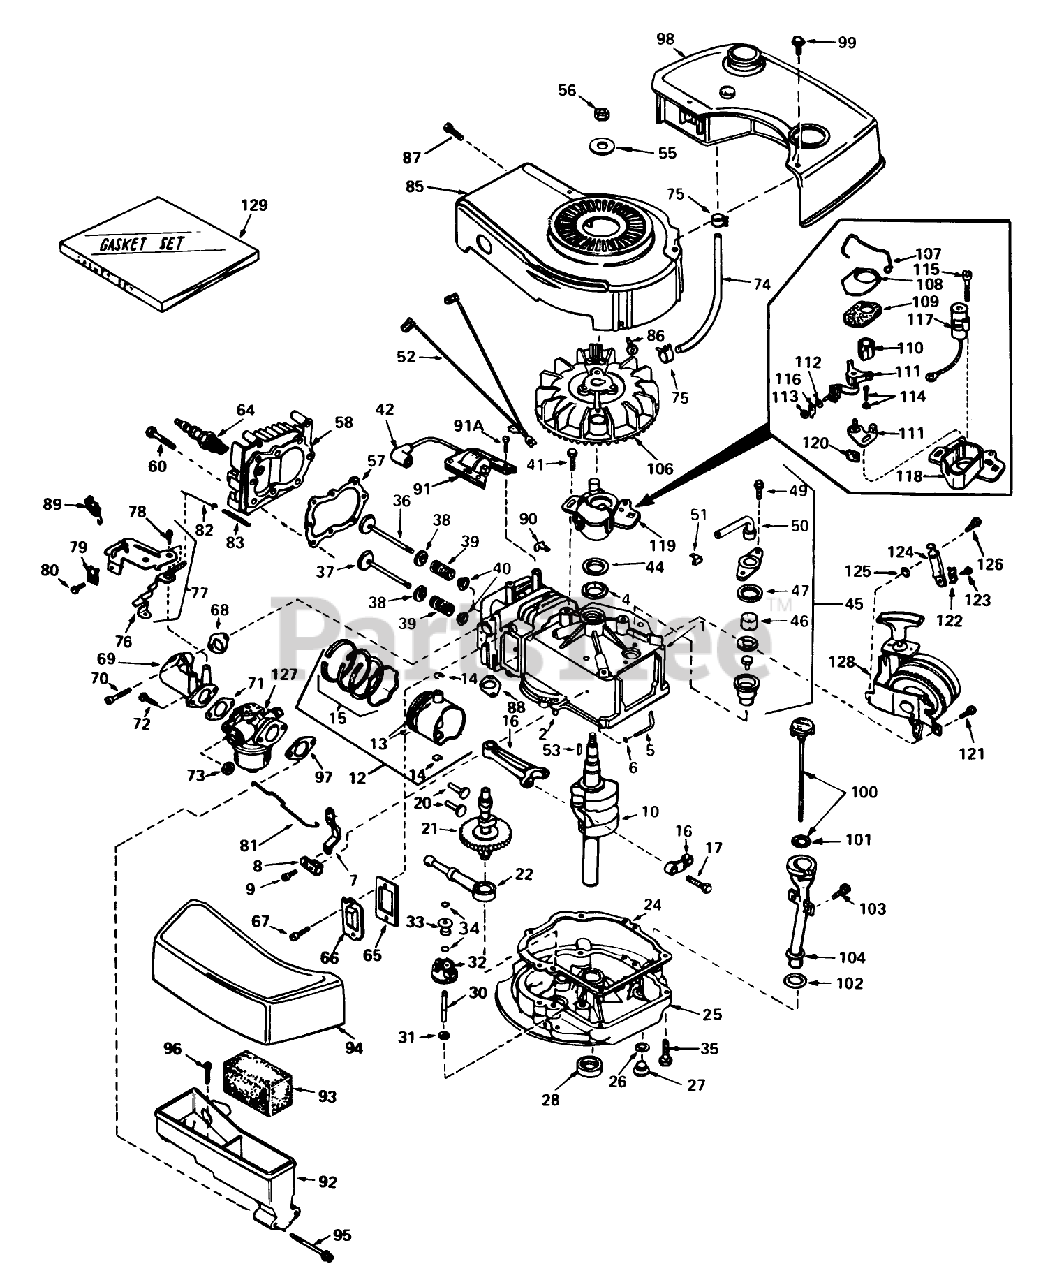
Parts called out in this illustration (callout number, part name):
1	Cyiinder Assy. (Incl. Ref. #2, 4 105)
2	Pin-Dowel
4	Seal-Oil
5	Rod, Governor (Incl. No. 36)
6	Washer-Flat
7	Governor Lever
8	Clamp-Lever, Governor
9	Screw
10	Crankshaft
12	Piston, Pin Ring Assy. (Std.)(Incl. Ref. #13A, 14 15)
12	Piston,Pin Ring Assy. (.010 over-size)(Incl. Ref. #13A, 14 15)
12	Piston, Pin Ring Assy. (Incl. Nos. 13A, 14 15)(.020 oversize)
13	Piston Pin Assy. (Incl . Ref. . #14) (Std.)
13	Piston Pin Assy. (Incl. Ref. #14) (.010 Oversize)
13	Piston Pin Assy. (.020 oversize) (Incl. Ref. #14)
14	Ring-Retaining, Piston Pin
15	Ring Set Piston (Std.)
15	Ring Set Piston (.010 Oversize)
15	Ring Set Piston (.020 Oversize)
16	Rod Assy., Connecting (Incl. Ref. #17)
17	Bolt-Rod, Connecting
20	Lifter-Valve
21	Camshaft(Mech.Comp. Release)
22	Oil Pump ASM
24	Gasket, Mounting
25	Flange Assy., Mounting (Incl. Ref. #26thru 30)
26	Gasket-Oil Drain
27	Plug Oil Drain
28	Seal Oil
30	Shaft-Governor
31	Washer-Flat
32	Governor Gear ASM
33	Spool-Governor
34	Ring-Retaining
35	Screw (1/4-20 x 1-1/4)
36	Valve, Intake (Incl. Ref. #38, 39 40) (Std.)
36	Valve, Exhaust (1/32" Oversize) (Incl. Nos. 8, 9 10)
37	Valve, Exhaust (Standard) (Incl. Nos. 8, 9 10)
37	Valve, Exhaust (1/32" Oversize) (Incl. Nos. 8, 9 10)
38	Cap-Upper Valve Spring
39	Spring-Valve
40	Cap-Valve, Spring
41	Screw
42	Cover-Spark Plug
44	Gasket Stator
45	Breather Assy. (Incl. Ref. #46, 47, 49, 50 51 )
46	Element-Breather
47	Gasket-Breather
49	Screw (10-24 x 9/16)
50	Tube, Breaker
51	Clip, Breather
52	Wire Ground
53	682488 LB GRASS HI-
55	Washer-Belleville
56	Nut-Flywheel
57	63573 GIL 42 SNWTHW
58	Dipper-Oil
60	Screw
64	Plug, Spark (J17LM or equiv.)
64	Plug, Spark (Champion RCJ-8)
65	Gasket-Breather
66	Cover-Valve
67	Screw
68	Gasket, Intake
69	Pipe, Intake
70	Screw (1/4-20 x 1)
71	Gasket-Carburetor
73	Nut and Lock Washer (1/4-28)
74	Line-Fuel
75	Clamp-Line, Fuel
76	Lever Control
77	Control Assy., Speed (Incl. Nos, 76, 78 89)
78	Screw, Hex Washer Hd Shoulder Self-Tap
79	Conduit
80	Screw (10-32 x 3/8)
81	Link-Throttle
82	Link Governor Spring
83	Spring Governor
85	Housing Blower
86	Screw
87	Screw (10-24 x 9/16)
88	Gasket Exhaust
89	Terminal
90	Clip-Wire
91	Lamination Coil Assy. (Incl. No. 42)
91A	Screw
92	Body Air Cleaner
93	Filer, Air
94	Cove, Air Cleaner
95	Screw Fil Hd.
96	Screw, Hex Hd.
97	Gasket-Air Cleaner
98	Tank, Fuel
99	Screw (10-32 x 35/64)
100	Dipstick, Oil (Incl. Ref. #101)(Twist Lock)
101	O-Ring
102	Gasket
103	Screw (10-32 x 1/2)
104	Tube-Oil Fill
106	Flywheel
107	Spring Breaker Box
108	Cover-Dust
109	Gasket-Dust Cover
110	Cam-Breaker
111	Breaker Assy.
112	Washer
113	DECAL
114	Breaker Screw
115	Condenser Screw
116	Terminal, Ground
117	Condenser
118	Stator Plate
119	Stator Plate Assy. (incl. Nos. 107, 111 thru 118 120)
120	Felt,Cam Wiper
121	Screw (1/4-20 x 1/2)
122	Conduit
123	Screw (10-32 x 3/8)
124	Bracker
125	Washer
126	Screw (1/4-20 X 5/8)
127	Carburetor (Incl. Ref. #71 )
128	Starter
129	53024/VAR.16HP O/P
